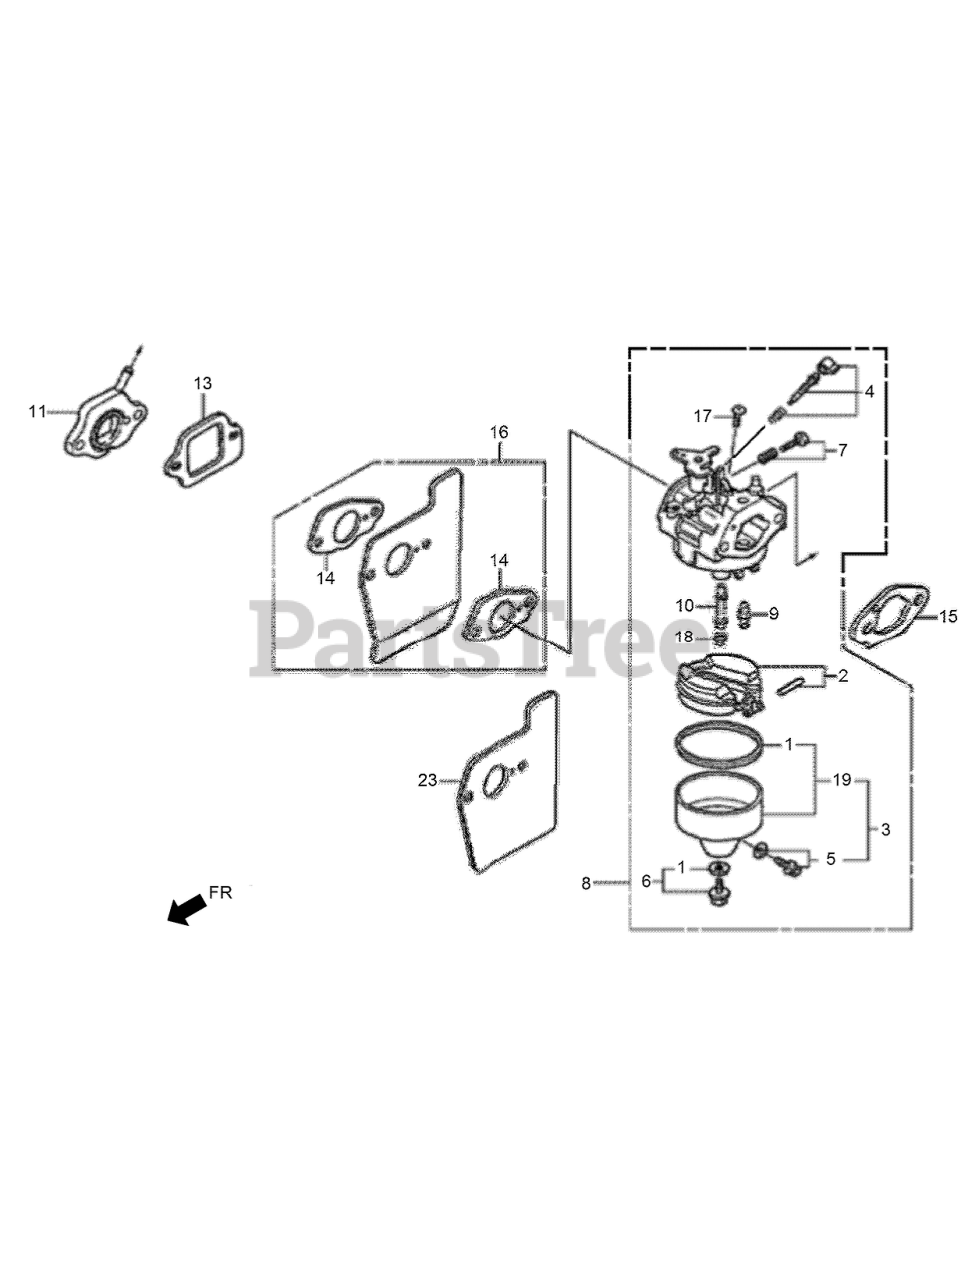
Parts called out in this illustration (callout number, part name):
1	PACKING SET
2	FLOAT SET
3	CHAMBER SET-FLOAT (CARBURETOR BB64G B)
4	SCREW SET
5	SCREW SET-DRAIN (CARBURETOR BB64G B)
6	SCREW SET
7	SCREW SET
8	CARBURETOR ASM (to S/N 2017060)
8	CARBURETOR ASM (from S/N 2017061 to 2932893)
8	CARBURETOR ASM (from S/N 2932894 to 4486248)
8	CARBURETOR ASM (from S/N 4486249)
9	VALVE-FLOAT (CARBURETOR BB64G B)
9	VALVE-FLOAT (CARBURETOR BB64G A)
10	NOZZLE-MAIN
11	CARBURETOR INSULATOR ASM
13	PACKING-INSULATOR
14	PACKING-CARBURETOR (to S/N 2937994)
15	PACKING-CARBURETOR
16	AIR GUIDE ASM (to S/N 2937994)
17	SCREW-PAN-5X6
18	JET-MAIN NO. 62
19	CHAMBER SET-FLOAT (CARBURETOR BB64G C)
23	GUIDE-AIR (from S/N 2937995)
